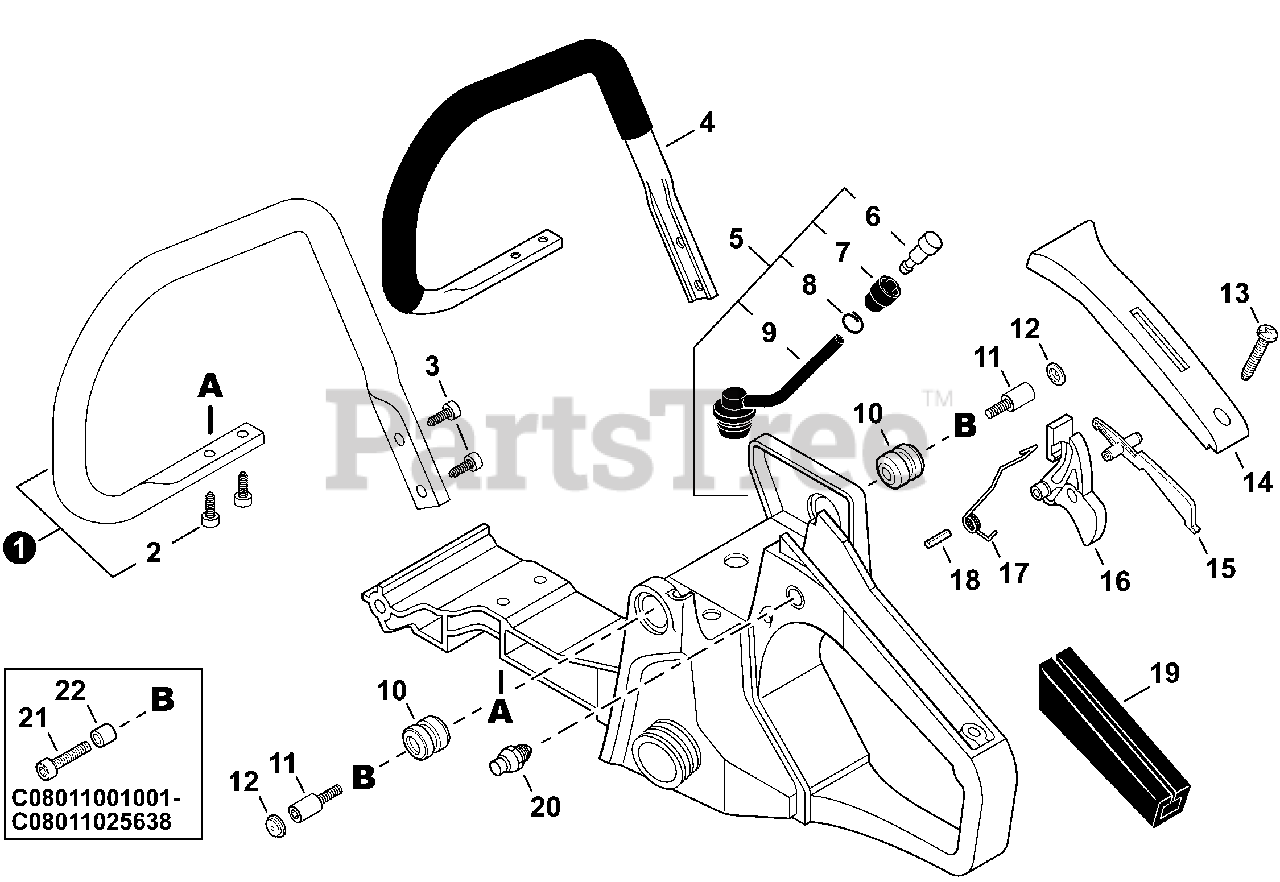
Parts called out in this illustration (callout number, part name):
1	HANDLE SET, FRONT - NYLON
2	SCREW TAPPING 5×20
3	SCREW TAPPING 5×20
4	HANDLE, FRONT - ALUMINUM
5	HANDLE ASSY, REAR
6	VENT ASSY
7	HOLDER, VENT
8	CLIP 6.5MM
9	PIPE, VENT 3×6×65
10	CUSHION 4
11	BOLT 4×10×13.5
12	CAP, CUSHION
13	SCREW 4×14
14	COVER, HANDLE
15	LOCKOUT, THROTTLE
16	TRIGGER, THROTTLE
17	SPRING, TORSION
18	PIN, SPRING 4×30
19	GRIP, HANDLE
20	LOCK, THROTTLE TRIGGER
21	BOLT 4×22
22	COLLAR 4
